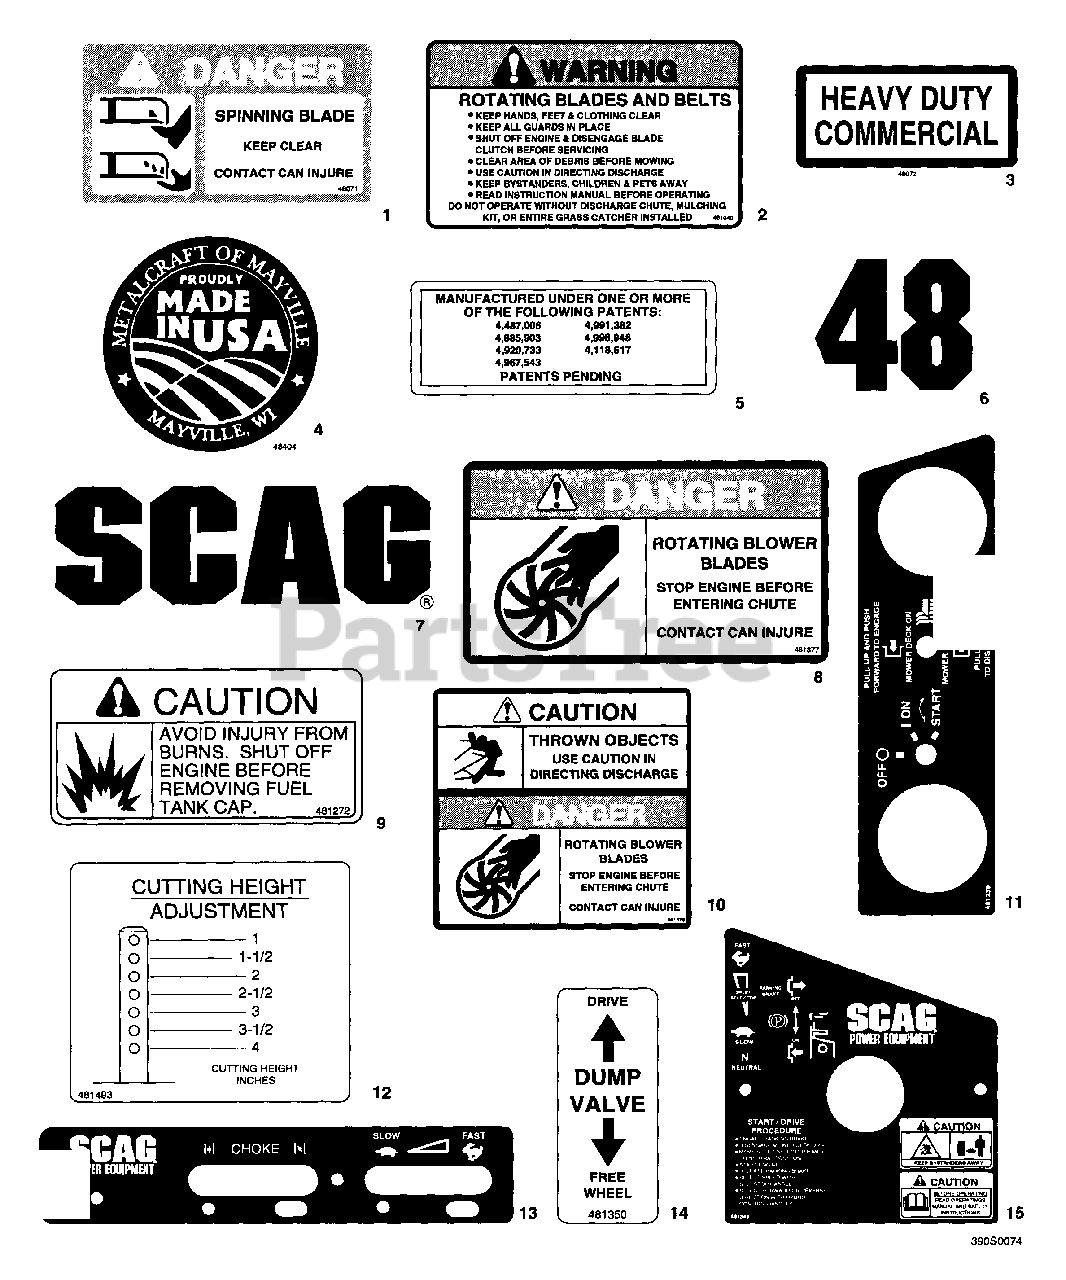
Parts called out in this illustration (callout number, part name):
1	Decal, Danger - Spinning Blades
2	Decal, Warning - Rotating Blades
3	Decal, Heavy Duty Commercial
4	Decal, Metalcraft - Made in USA
5	Decal, Patent
6	Decal, 48
7	Decal, Scag
8	Decal, Danger - Rotating Blower Blades
9	Decal, Fuel Tank
10	Decal, Caution/Danger - Thrown Objects
11	Decal, Instrument Panel - Upper
12	Decal, Cutting Height
13	Decal, Instrument Panel - Lower
14	Decal, Dump Valve
15	Decal, R.H. Fender
